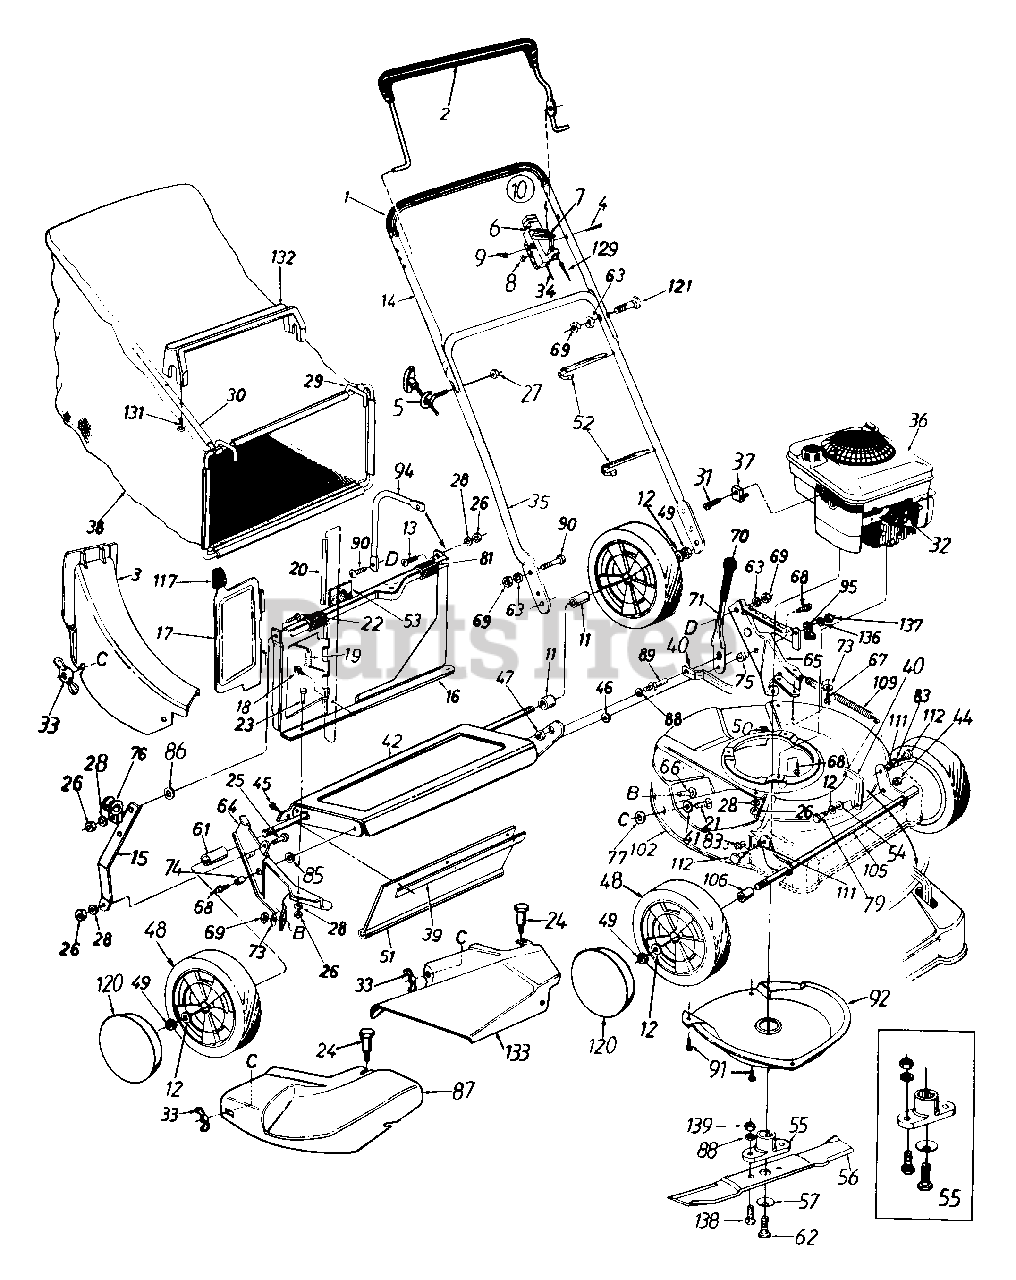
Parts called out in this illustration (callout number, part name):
1	Grip
2	Control Handle Ass'y. - L.H.
3	Top Discharge Chute Ass'y.
4	Oval C-Sunk Scr.
5	Rope Guide Bolt
6	Throttle Body
7	Throttle Lever
8	Spr. Wash. .66" I.D.
9	Hex L-Nut 1/4-20 Thd.
10	Throttle Box Comp.
11	Spacer .526" I.D. x .690" O.D. x 640" Lg
12	Fl. Wash. .385" I.D. x .87" O.D.
13	Truss Mach. Scr. 1/4-20 x .62"
14	Upper Handle
19	Torsion Spring
20	Pivot Pin
21	Carriage Bolt 1/4-20 x .62"
22	Truss Mach. Scr. 1/4-20 x .75"
23	Hex Bolt 1/4-20 x .50" Lg.
24	Shoulder Bolt .312" Dia. x .18" Lg.
25	Hex Bolt 1/4-20 x .62" Lg.
26	Hex Nut 1/4-20 Thd.
27	Hex L-Nut 1/4-20 Thd.
28	L-Wash. 1/4" I.D.
30	Upper Bag Support
31	Hex Self-Tap Scr. #10-32 x .62"
32	Spark Plug Insulator
33	Wing Nut w/Washer
34	Throttle Control Wire 61"
35	Lower Handle
37	Cable Clamp
38	21" Top Discharge Grass Bag
39	Retaining Strip
40	Height Adj. Connecting Arm
41	Fl-Wash. .344" I.D. x .62"
45	Hex AB-Tap Scr. 1/4 x .62"
46	Fl-Wash. .38" I.D. x 1.0"
47	Hex Jam Nut 3/8-24 Thd. Wheel Ass'y. Comp.
48	Wheel Ass'y. Comp. 8 x 1.75 "T" Tread
49	Hex Ins. Top L-Nut 3/8-16 Thd.
51	Rear Flap 3.75" x 17.30" Lg.
52	Cable Tie
53	Foam Strip 1" Lg.
54	Bell-Wash. .515" I.D. x 1" O.D.
55	Blade Adapter Kit
56	21" Blade
57	Bell-Wash. .46" I.D.
61	Sleeve .526" I.D. x .69"
62	Hex Nut 3/8-24 Thd.
63	L-Wash. 5/18" I.D.
64	R.H. Handle Wheel Brkt. Ass'y.
65	L.H. Handle Wheel Brkt. Ass'y.
66	Carriage Bolt 5/16-18 x .62"
67	Hex Wash. Hd. B-Tap Scr. 5/16-18
68	Hex Wash. Hd. TT-Tap Scr. 3/8-1 6
69	Hex Nut 5/16-18 Thd.
71	Height Adj. Lever
73	Bell-Wash. 5/16" I.D.
74	Spacer .383" I.D. x .503" O.D.
75	Shld. Spacer .500" Dia.
76	Rope Guide
77	Bolt Retainer 1/4 x .50" O.D.
79	Shld. Bolt .5" Dia. x .295"
81	Panel Clip
83	Flanged Nyliner Brg.
85	Fl-Wash. 3/8" I.D. x 1" O.D.
86	Fl-Wash. .285" I.D. x 1.25" O.D.
87	Mulching Plug
88	L-Wash. 3/8" I.D.
89	Shld. Pin 3/8-24 x 1.43" Lg.
90	Truss Mach. Scr. 5/16-18 x .75"
91	Hex Wash. Hd. Tap Scr. 1/4 x .5" Lg.
92	Mulching Baffle
94	Catcher Panel Support Arm
95	Clamp
106	Sleeve .526" I.D. x .69" O.D.
109	Extension Spring 8" Lg.
111	Internal L-Wash. 3/8" I.D.
112	Shld. Bolt .575" Dia. x .42"
117	Door Grip
120	Hub Cap
121	Curved Carr. Bolt 5/16-18 x 1.38" Lg.
129	Control Cable - 47" Lg.
131	Hex AB-Tap Scr. #12 x 1.0"
132	Bag Handle
133	Side Chute Deflector Ass'y.
136	Fl-Wash. .385" I.D. x .87" O.D.
137	Hex Patch L-Nut 3/8-24 Thd.
